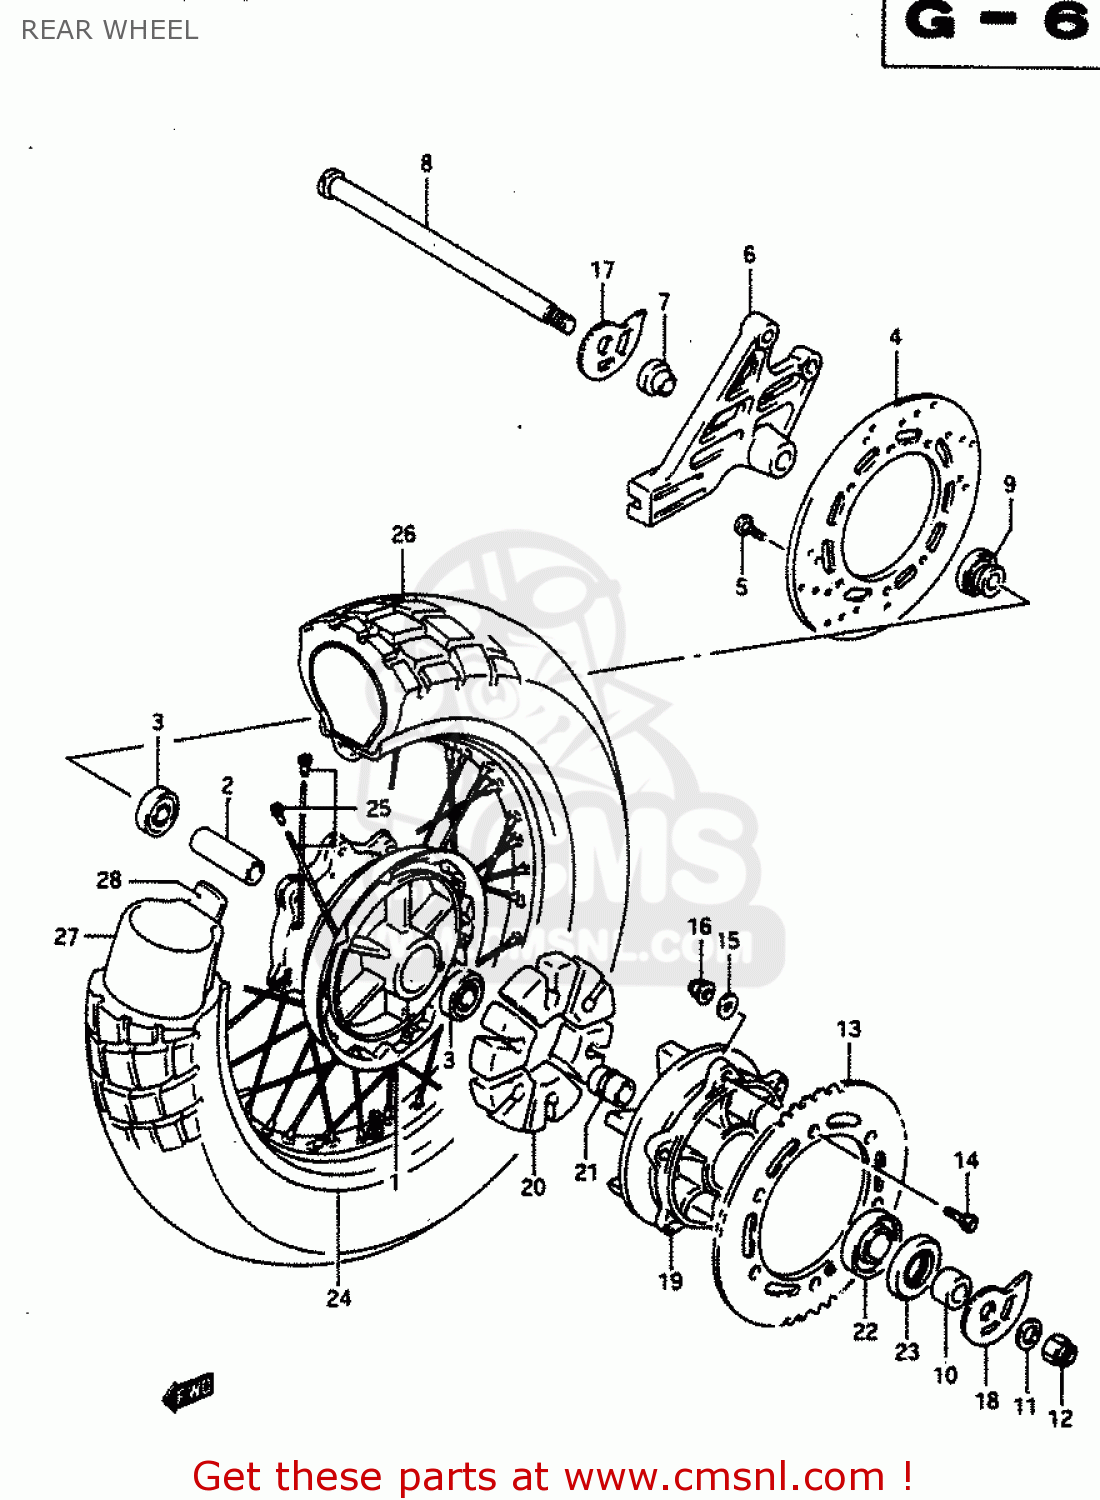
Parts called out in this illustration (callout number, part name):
1	HUB COMP,REAR WHEEL
2	SPACER(17.5X25X78)
3	BEARING
4	DISC,RR BRAKE
5	BOLT,BRAKE DISC
6	BRACKET,RR CALIPER
7	SPACER (17X21X10)
8	AXLE,RR
9	SPACER,RR AXLE,L
10	SPACER(17X33X22.4)
11	WASHER (17X30X3.2)
12	NUT
13	SPROCKET,REAR
14	BOLT(8X30.5)
15	WASHER
16	NUT
17	ADJUSTER,CHAIN
18	PLATE,CHAIN ADJUSTER
19	DRUM,REAR SPROCKET
20	ABSORBER,RR HUB SHOCK
21	RETAINER,RR SPROCKET DRUM
22	BEARING(25X62X17)
23	SEAL,OIL(33X62X7)
24	RIM,REAR WHEEL (17XMT2)
25	SPOKE SET,RR
26	TIRE
27	TUBE ASSEMBLY,WHEEL,INNER
28	PROTECTOR,WHL INR TUBE
